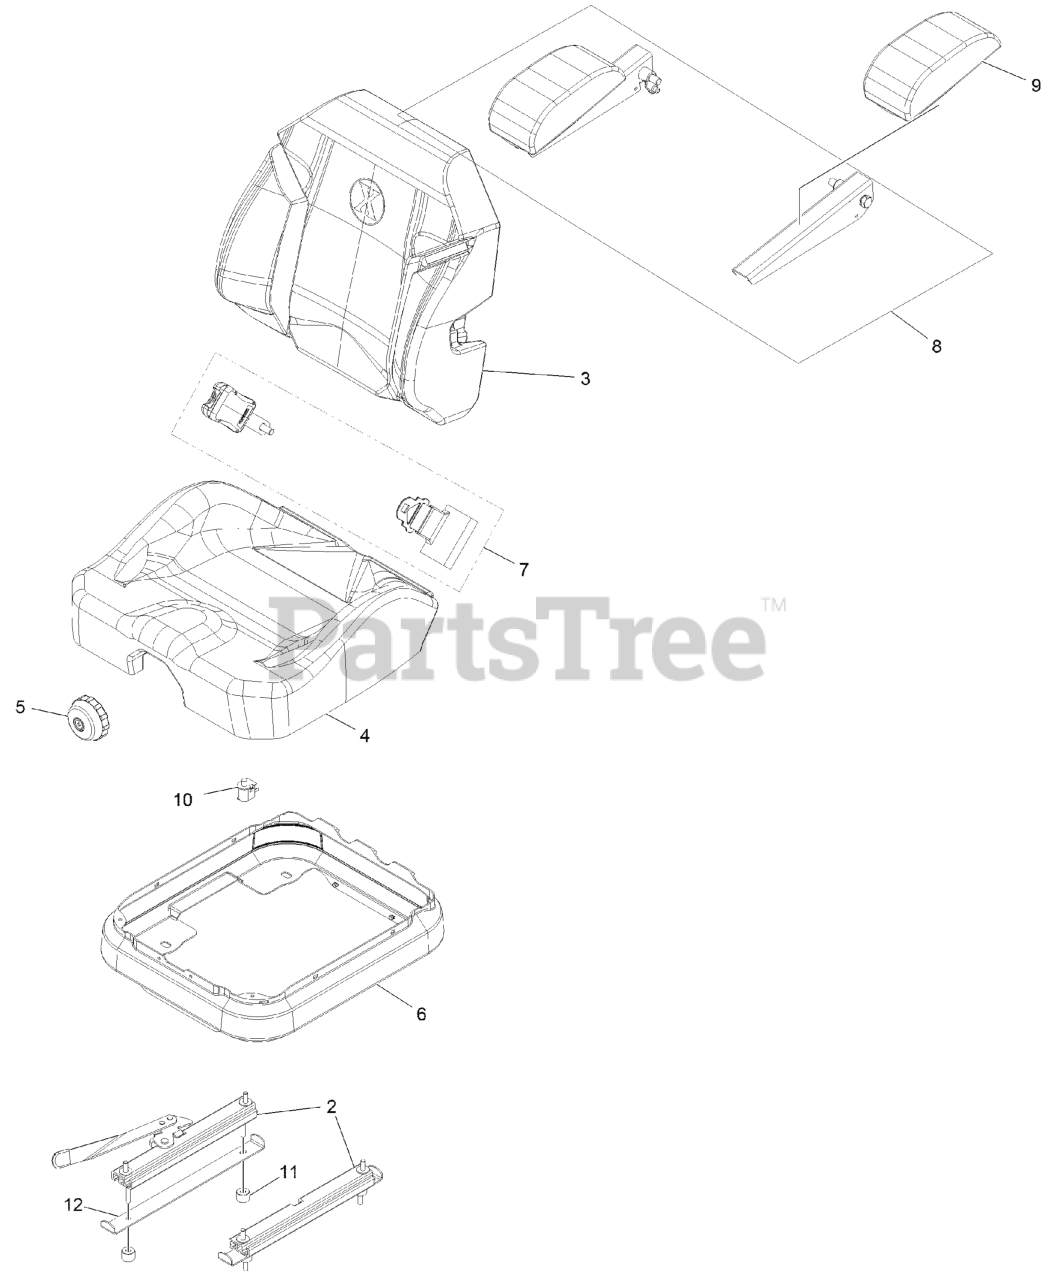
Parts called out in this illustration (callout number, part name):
2	SEAT TRACK SET
3	COVER-BACK 311463VN500
4	COVER-CUSHION 311464VN500
5	KNOB-ADJUSTER
6	COVER-SUSPENSION, BELLOWS
7	SEAT BELT SERVICE KIT
8	KIT-ARM REST SET
9	KIT-ARM REST PADS
10	SWITCH-BAIL
12	STOP, SEAT
